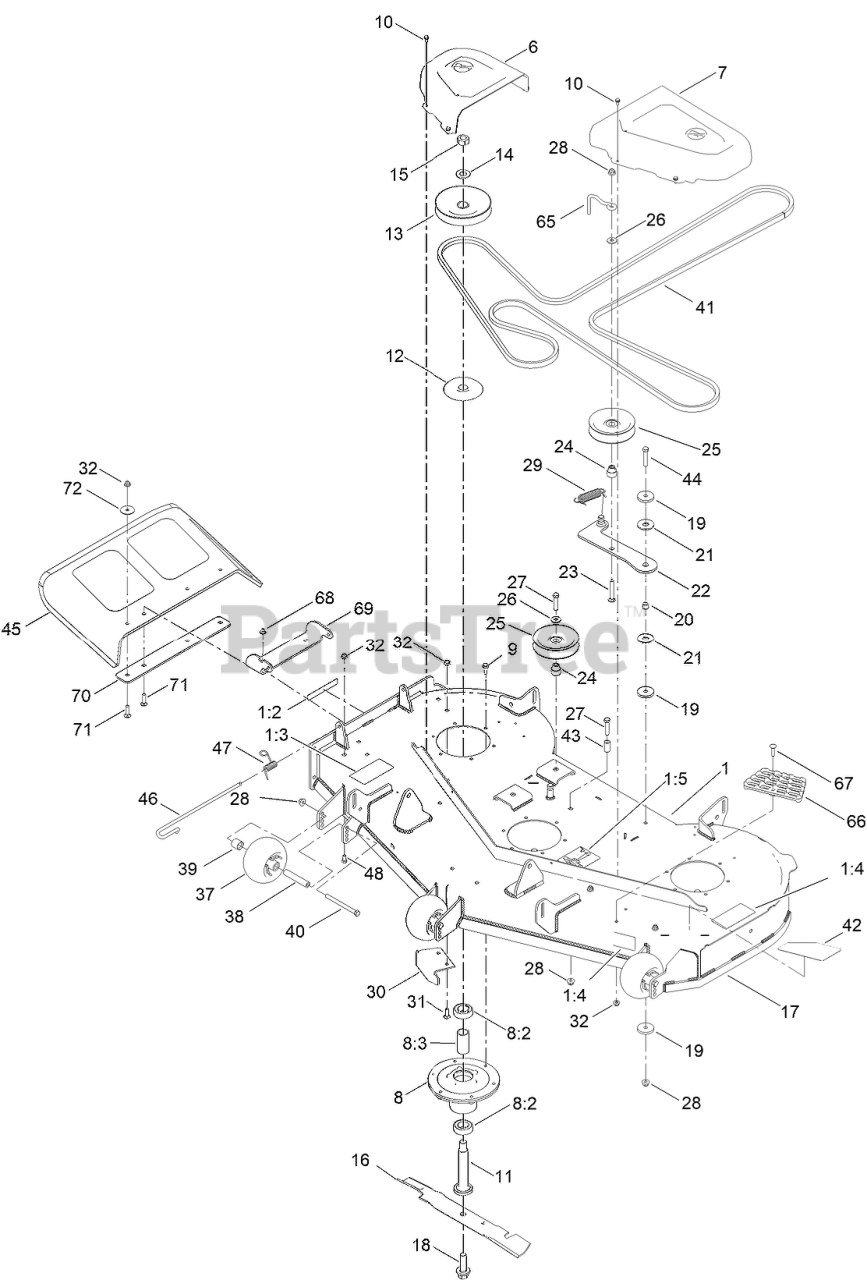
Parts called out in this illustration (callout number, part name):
1	54in DECK ASM
1:2	DECAL-DANGER
1:3	DECAL-DANGER, DECK
1:4	DECAL-SCALP, ANTI
1:5	DECAL-ROUTING, BELT
6	COVER-BELT, RH
7	COVER-BELT, LH
8	SPINDLE ASM
8:2	BEARING-BALL
8:3	SPACER-BEARING
9	SCREW-TAPTITE
10	SCREW-HWH
11	SHAFT-SPINDLE
12	SHIELD-BEARING
13	PULLEY
14	WASHER
15	NUT-HEX
16	BLADE-HI FLO
17	WASHER-BELLEVILLE
18	SCREW-BLADE
19	WASHER-PLAIN
20	SPACER
21	WASHER-FRICTION, COMPOSITE
22	IDLER ARM ASM
23	SCREW-CARR
24	BUSHING-IDLER
25	PULLEY-IDLER, FLAT
26	WASHER-HARDENED
27	SCREW-HH
28	NUT-HF, NI
29	SPRING-EXTENSION
30	BAFFLE-CUTOFF
31	SCREW-CARR
32	NUT-HF, NI
37	ROLLER-SCALP, ANTI
38	TUBE-SPANNER
39	SPACER-AXLE, REAR
40	SCREW-HH
41	V-BELT
42	DECAL-DECK
43	SPACER-FENDER
44	SCREW-HH
45	DEFLECTOR
46	PIN-CHUTE
47	SPRING-TORSION
48	SCREW-HH
65	GUIDE-BELT, IDLER
66	STEP-DECK
67	BOLT-CARRIAGE
68	NUT-HF, NI
69	BRACKET-DEFLECTOR, UPPER
70	PLATE-DEFLECTOR
71	SCREW-CARR
72	WASHER-FLAT
